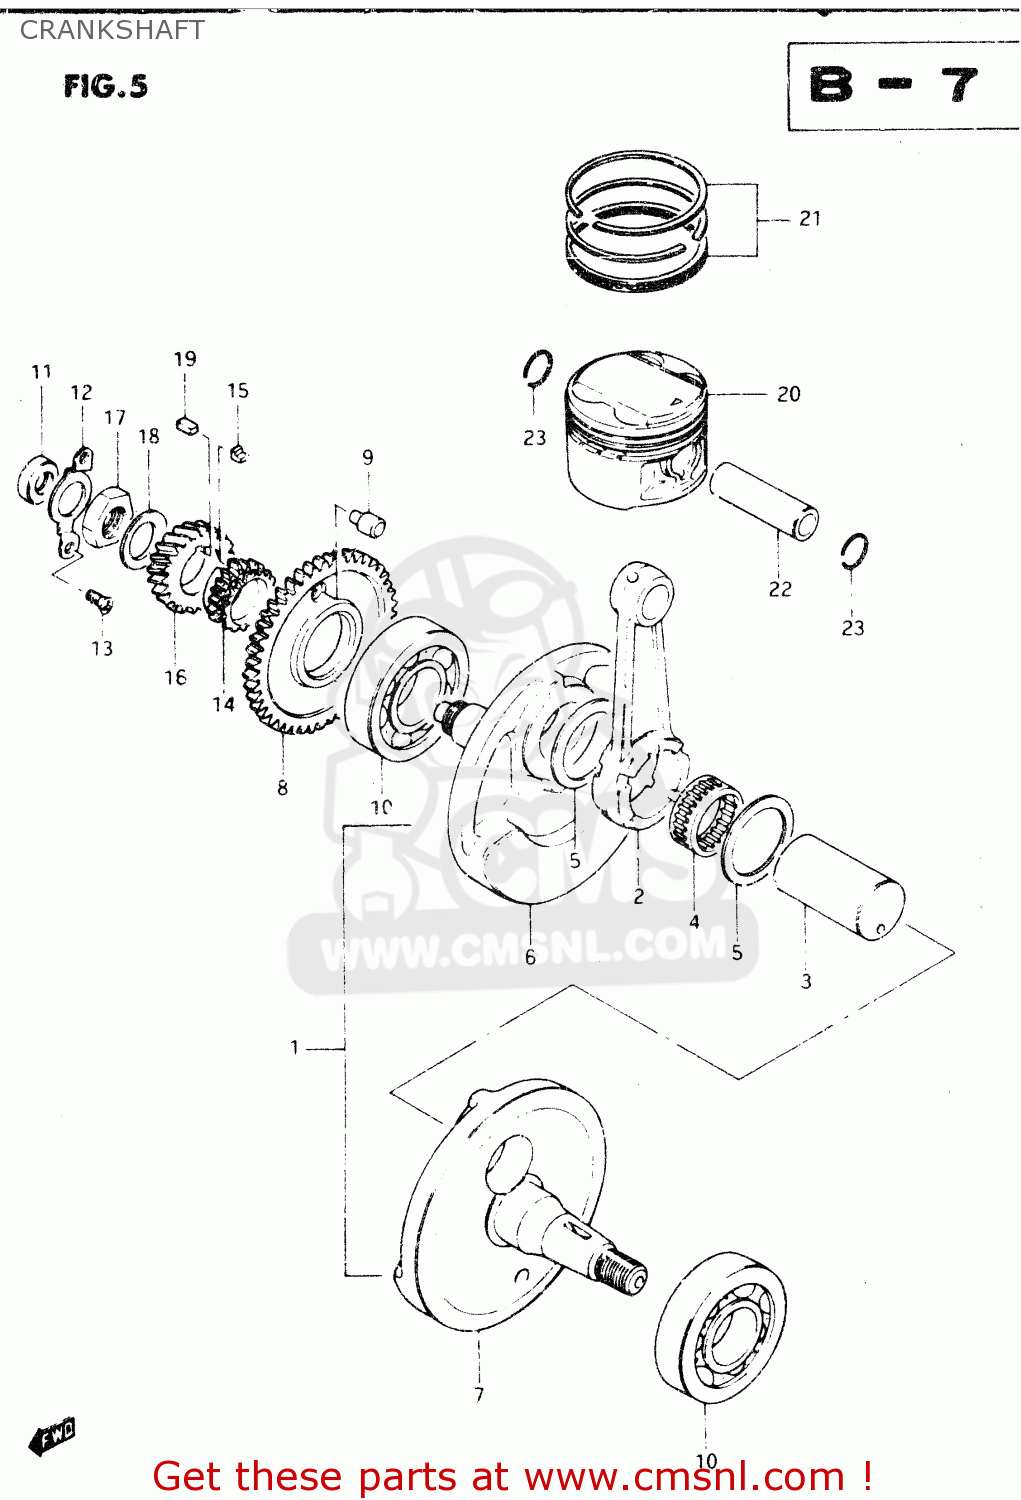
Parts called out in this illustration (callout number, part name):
1	CRANKSHAFT ASSEMBLY
2	CONNECTING ROD
3	PIN,CRANK
4	BEARING
5	WASHER(31X48.5X1)
6	CRANKSHAFT,R
7	CRANKSHAFT,LEFT
8	GEAR,CRANK BALANCER DRIVE
9	PIN
10	BEARING
11	SEAL,OIL(14X26X6)
12	RETAINER,CRANKSHAFT BEARING,R
13	SCREW
14	SPROCKET,CAM CHAIN DRIVE(NT:21
15	KEY,SPROCKET
16	GEAR,PRIMARY DRIVE NO.21
17	NUT (20MM)
18	WASHER
19	KEY
20	PISTON
21	RING SET,PISTON
22	PIN,PISTON
23	CIRCLIP,PISTON PIN
